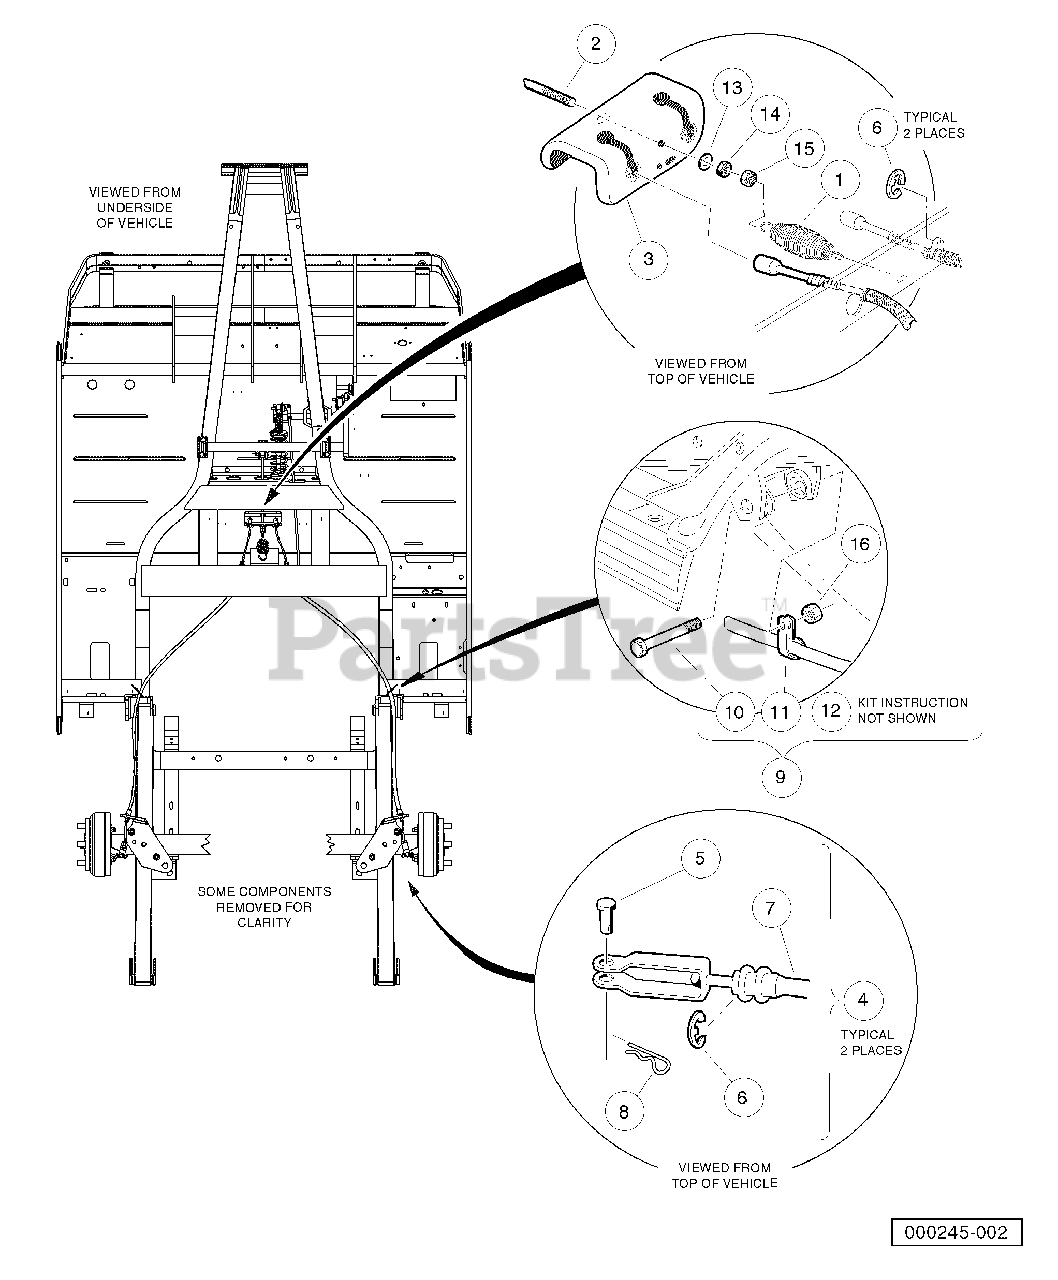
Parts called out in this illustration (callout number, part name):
1	Spring, Brake Return
2	Rod, Equalizer
3	Equalizer Bracket
4	Brake Cable Kit
5	Pin, Clevis, 5/16 X 3/4
6	E-Clip, 1/2
7	Cable, Brake
8	Pin, 3/32 X 1.00 Sq Cut Cotter
9	Kit, Field P-clamp, Brake Line
10	Screw, 3/8-16 X 3.50 Hex Cap
11	P-clamp, Brake Line
12	Instr Fd. P-clamp, Brake Line
13	Washer, 5/16 Type A Flat
14	Nut, 5/16-18 Hex
15	Locknut, 5/16-18 Nylon Insert
16	Locknut, 3/8-16 Hex
